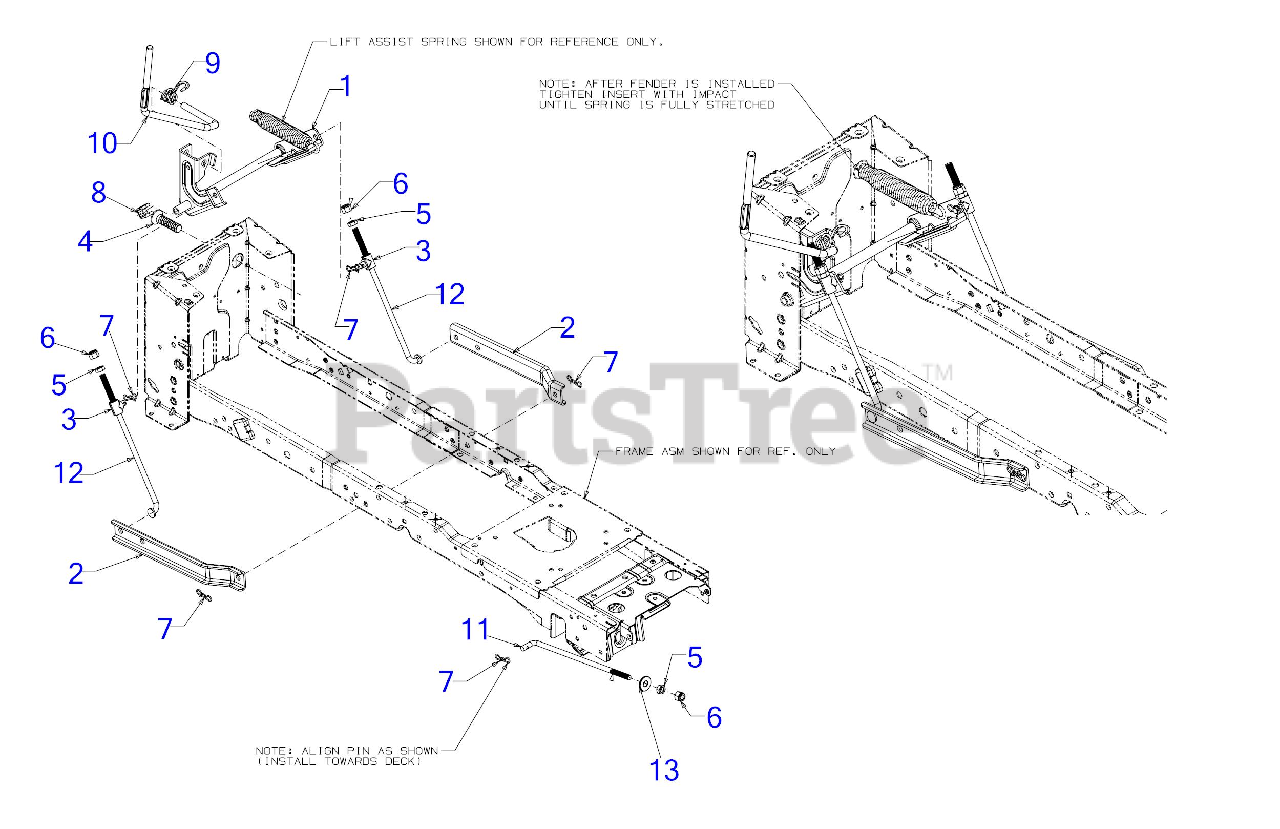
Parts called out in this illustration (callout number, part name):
1	LIFT SHAFT ASSEMBLY
3	LIFT ROD FERRULE
4	LIFT SPRING INSERT
5	HEX NUT
6	HEX LOCK NUT NYLON
7	BOW TIE COTTER PIN
8	SPACER-LIFT SHAFT
9	TORSION SPRING
10	DECK LIFT HANDLE
11	DECK FRONT LIFT ROD
12	ADJUSTMENT LIFT ROD
13	DECK LIFT PIVOT CUP
